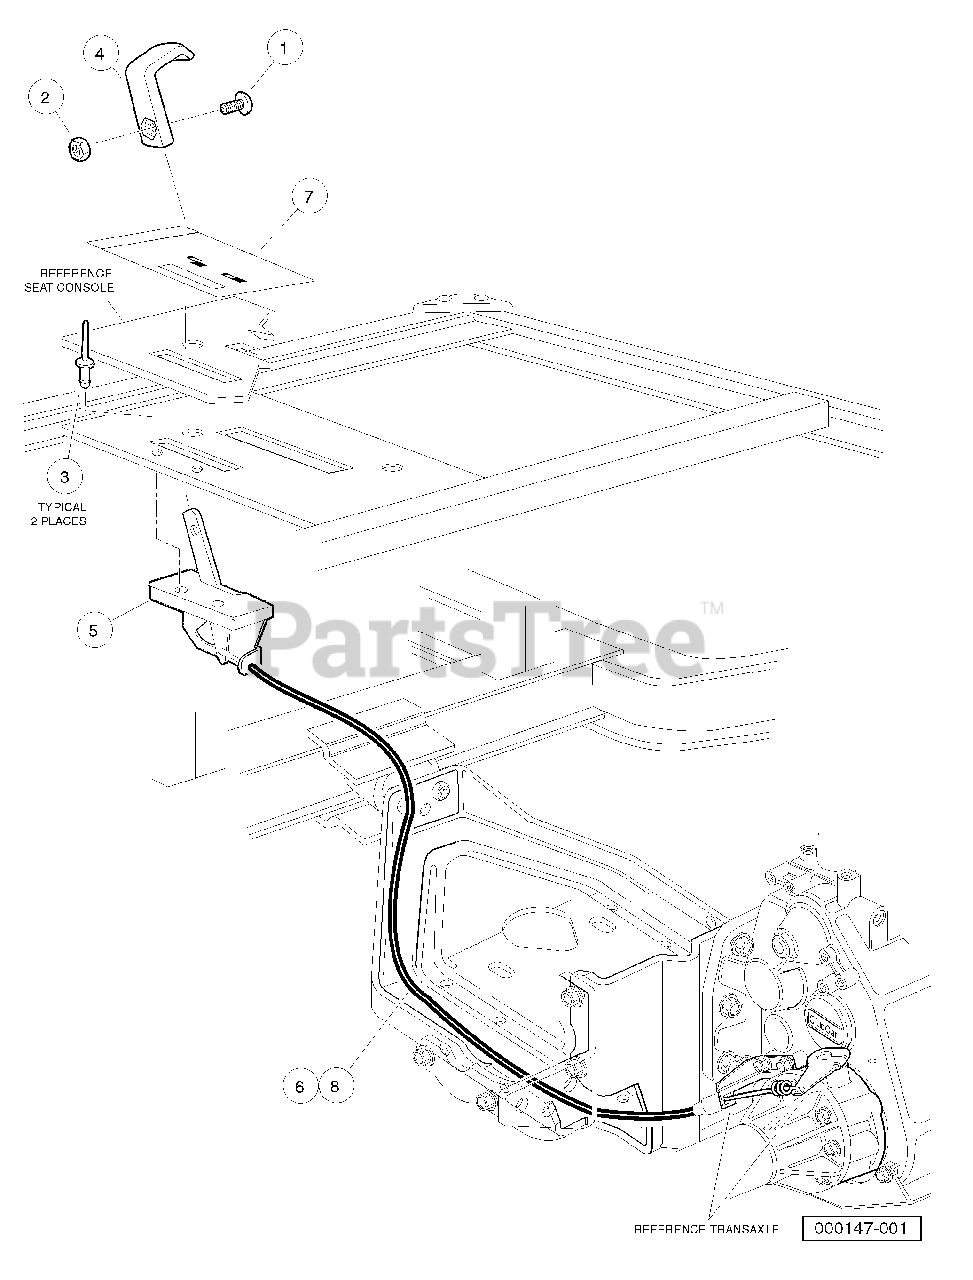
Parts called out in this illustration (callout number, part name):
1	Screw, #8-32 X 0.375
2	Nut, #8-32 Hex
3	Rivet, 3/16, Stainless-Steel, Pop
4	Handle, Differential Lock Red
5	Differential Lock Controller
6	Differential Lock Cable
7	Decal, Differential Lock Warning
8	Cable, Differential
